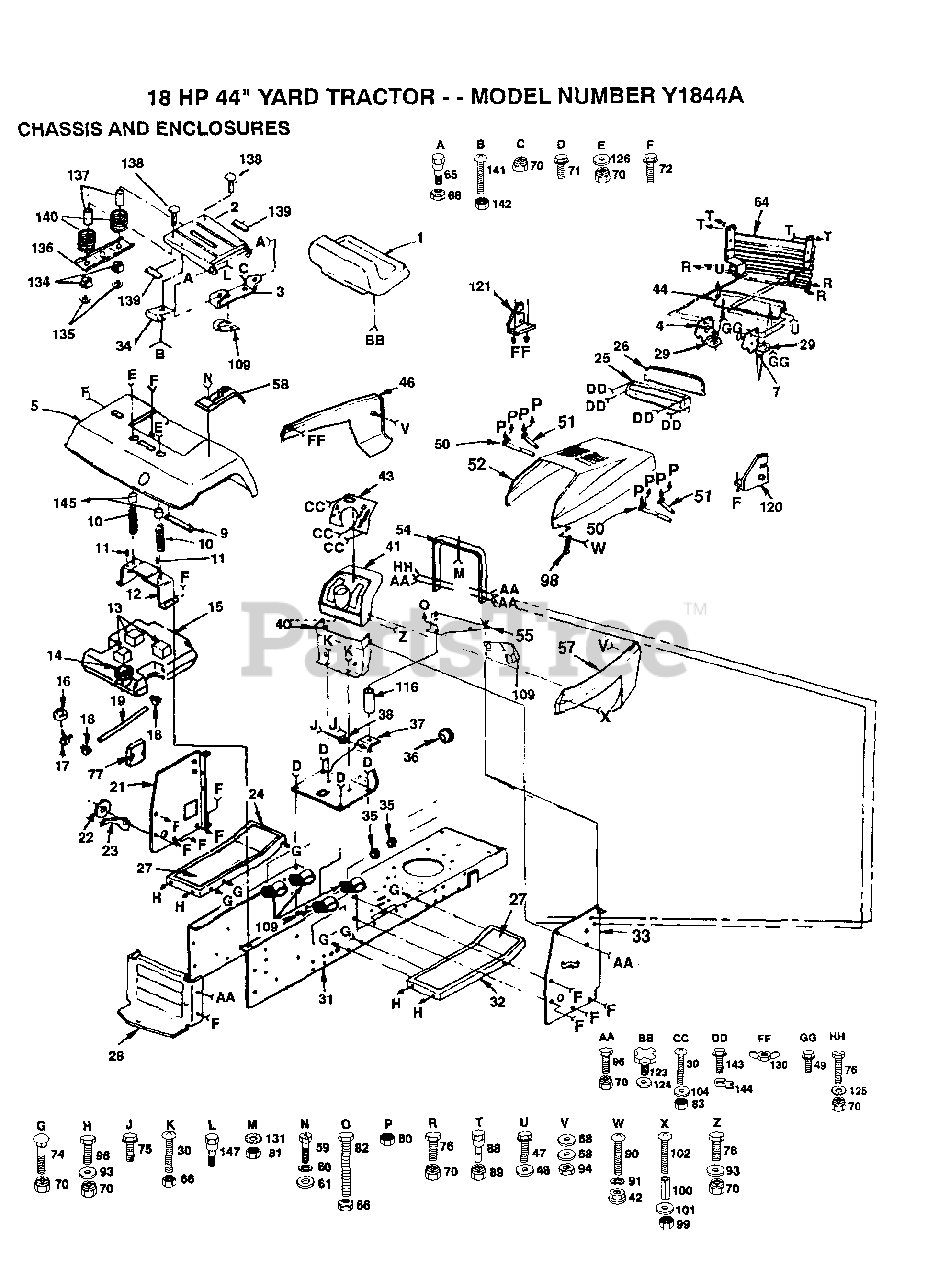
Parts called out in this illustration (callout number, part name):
4	SUPPORT LH YTH
5	FENDER
7	SUPPORT RH YTH
10	SPRING COMPRESSIO
11	NUT-PUSH YT
13	PAD-SPACER LT
16	BUSHING OUTLET T
17	FUEL TANK STEM GT
18	HOSE CLAMP
19	FUEL LINE T
21	PANEL DASH LH
22	WASHER T
26	LENS LT
27	FOOTREST PAD
28	DRAW BAR
29	WASHER
30	SCREW
31	CHASSIS
33	DASH PANEL RH
36	SNAP BUSHING T
38	BUSHING STEERING
40	LOWER DASH
42	WELDNUT
47	SCREW
48	WASHER
49	SCREW
54	SUPPORT ASS'Y
57	"PANEL,SIDE RH "
58	CONSOLE SHIFTER
59	SCREW
60	"WASHER,LOCK"
61	WASHER
68	WASHER PM
71	SCREW LT
72	SCREW
74	BOLT
76	BOLT
77	COVER ACCESS
80	NUT
82	BOLT
90	SCREW
91	LOCKWASHER
93	WASHER
98	HOOD LATCH T
100	SPACER LT
101	WASHER
102	SCREW
104	WASHER
109	CLIP T
116	SPACER
120	SUPPORT RH YTH
121	SUPPORT LH YTH
123	"KNOB 1/2"" YT"
124	WASHER
125	LOCKWASHER
126	WASHER
134	BUSHING
136	BRKT SWITCH
137	SPACER SPLIT
139	STRIP FORM
140	SPRING COMPRESSED
142	"NUT,KEPS"
144	"""J"" FASTENER LT"
145	CAP SPRING
147	"BOLT,SHOULDER"
